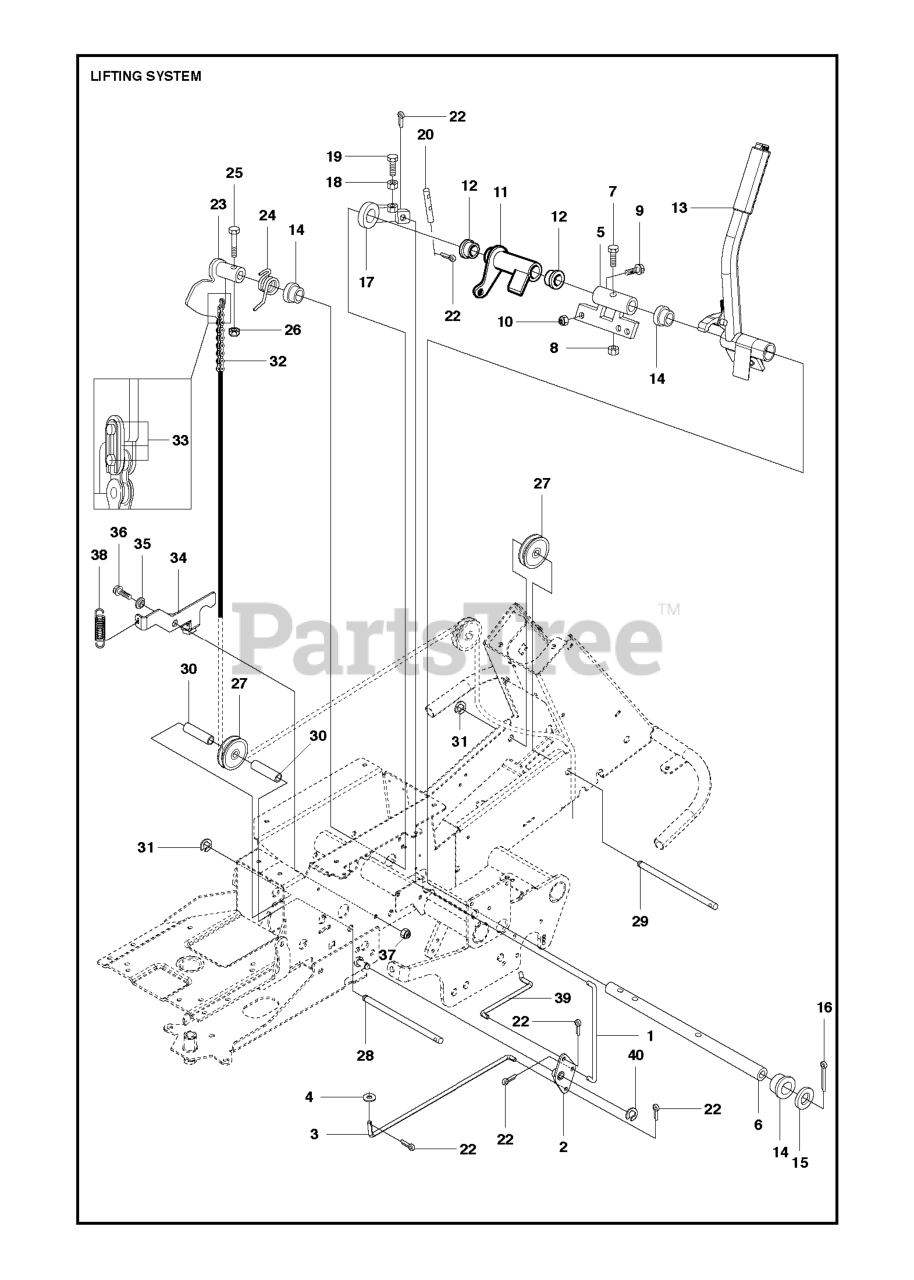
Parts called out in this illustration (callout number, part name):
9	SCREW M6S 8X25
10	NUT
12	BEARING FLANGE
13	LIFTING LEVER ASSY
14	BEARING FLANGE
17	LEVER CLUTCH
18	NUT
35	WASHER
36	BOLT
37	LOCKNUT M8
40	RETAINING RING
